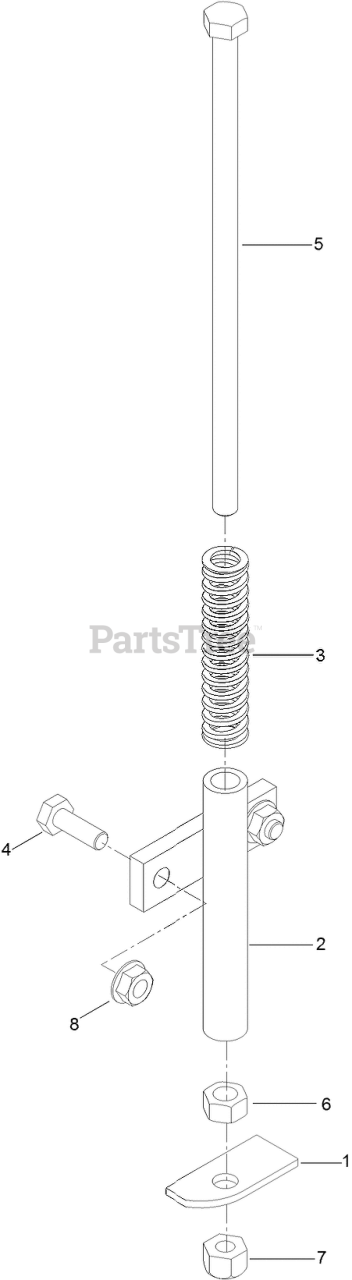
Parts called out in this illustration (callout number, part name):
1	Plate-Switch
2	MOUNT-SPRING, SEAT
3	SPRING-SWITCH, SEAT
4	SCREW-HH
5	SCREW-HH
6	NUT-HEX
7	NUT-LOCK, NI
